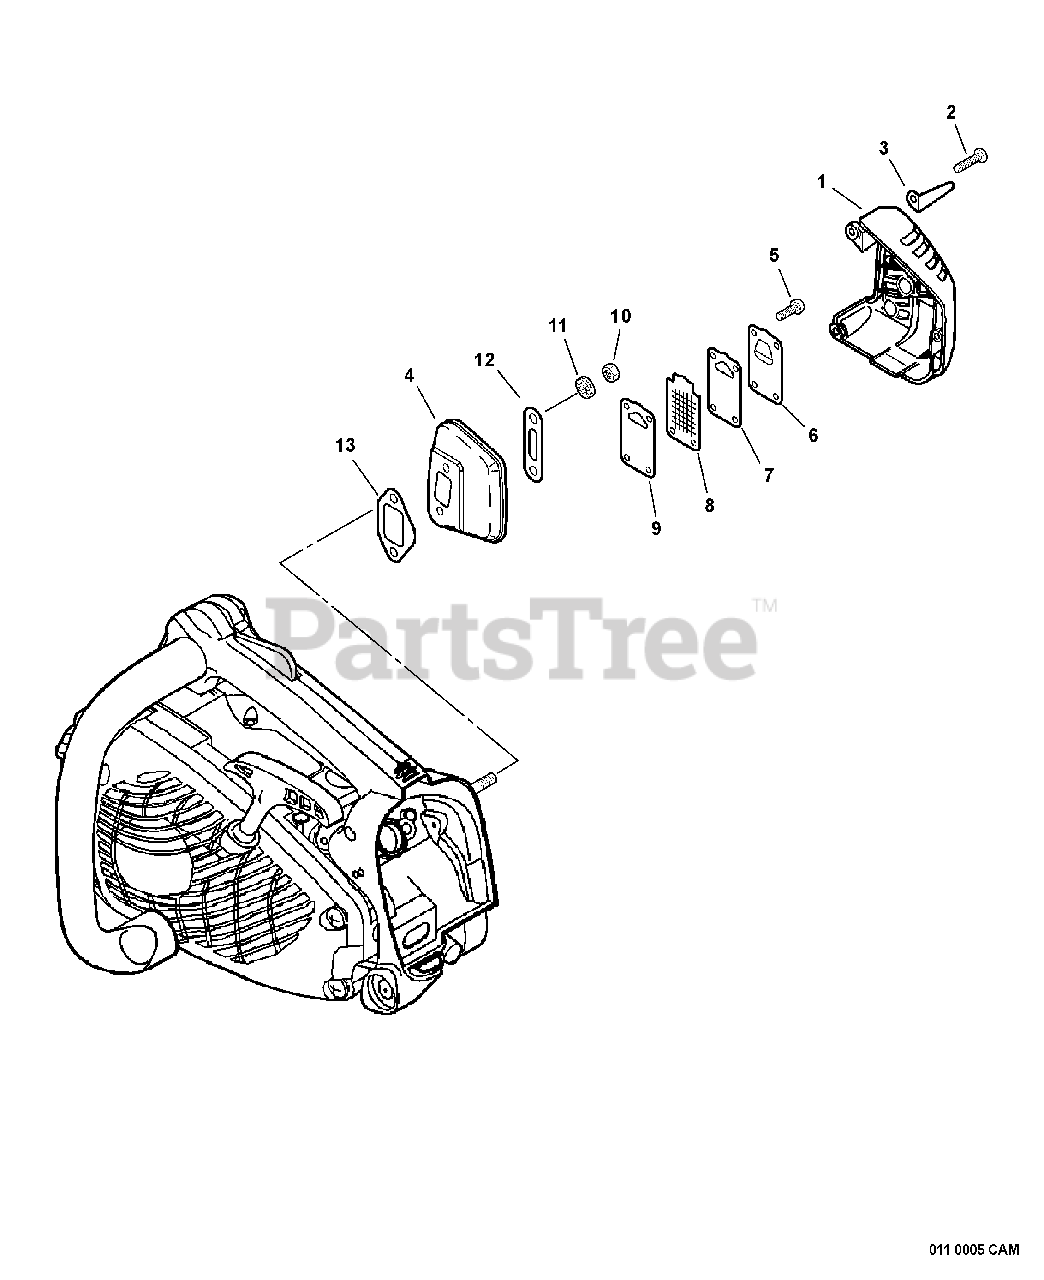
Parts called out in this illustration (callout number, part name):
1	COVER, MUFFLER
2	SCREW 4×16
4	MUFFLER
5	SCREW 4×12
6	OUTLET, EXHAUST
7	GASKET, EXHAUST
8	SCREEN, SPARK ARRESTER
9	GUIDE, EXHAUST
10	NUT M5
12	PLATE, EYE
13	GASKET, EXHAUST
